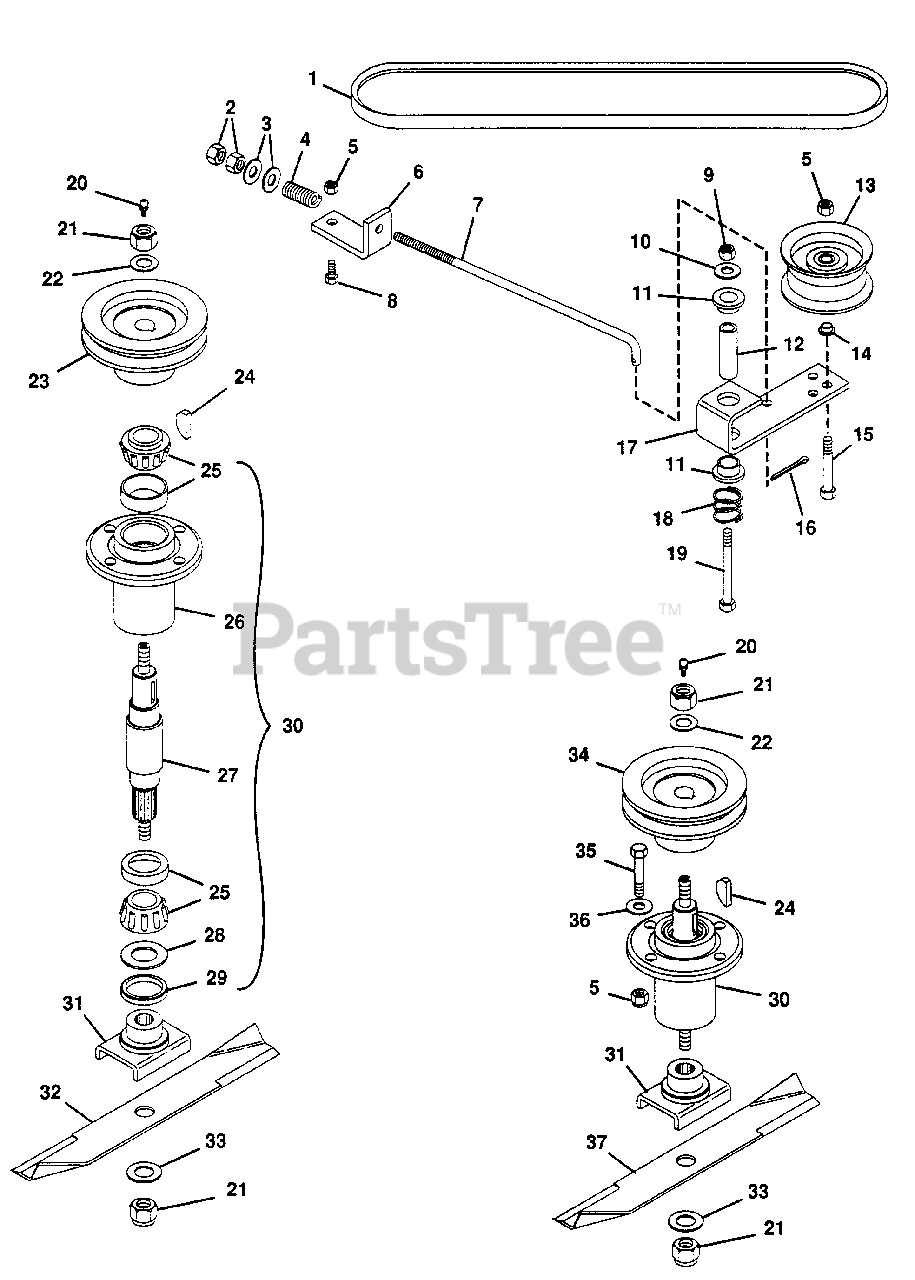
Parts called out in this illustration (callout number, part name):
1	BELT, PRO-32 MOWER
2	NUT, HEX 3/8-24
3	WASHER, FLAT .406X.812X.065
4	SPRING, COMP. 1X.78X338 LB/N
5	NUT, LOCK 3/8-16
6	BRACKET, BELT TENSIONER
7	ROD, IDLER
8	BOLT, HEX 3/8-16X.875
9	NUT, LOCK 1/2-13
10	WASHER, FLAT .531X1.250X.100
11	BUSHING, FLANGE NYLON
12	BUSHING, ST. .560X.750X2.44 STL.
13	PULLEY, IDLER
14	BUSHING, FLANGE BRONZE
15	BOLT, HEX 3/8-16X2.25
16	PIN, COTTER .09X.75
17	ARM, IDLER PIVOT
18	SPRING, COMP. 1X.80X36 LB/N
19	BOLT, HEX 1/2-13X3.25
20	FITTING, LUBE 1/8
21	NUT, LOCK 5/8-11
22	WASHER, FLAT .687X1.312X.122
23	SHEAVE, SPINDLE
24	KEY, WOODRUFF 1/4X1 HARD #15
25	ASSEMBLY, BEARING
26	HOUSING, BEARING
27	SHAFT, SPINDLE
28	WASHER, FLAT .975X1.970X.030
29	SEAL, STEEL
30	ASSEMBLY, SPINDLE
31	WELDMENT, BLADE CRADLE
32	BLADE
33	WASHER, FLAT .656X1.312X.095
34	SHEAVE, SPINDLE
35	BOLT, HEX 3/8-16X1.25
36	WASHER, FLAT .438X1.000X.083
37	BLADE
